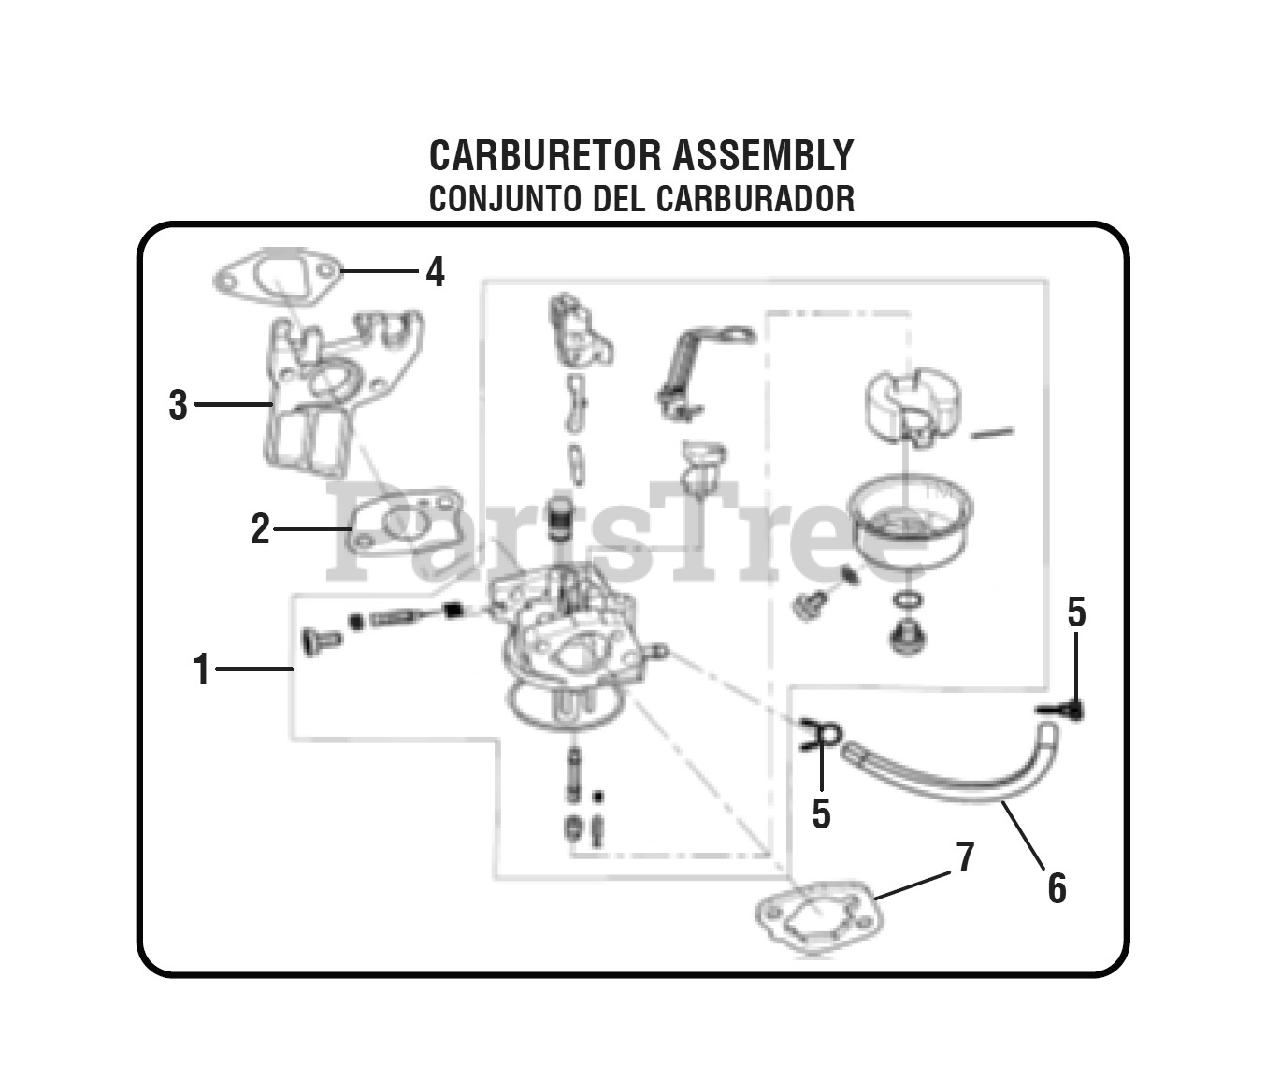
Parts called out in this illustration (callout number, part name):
1	Carburetor Assembly
2	Carburetor Gasket
3	Carburetor Insulator Plate
4	Carburetor Insulator Gasket
5	Clamp
7	Air Cleaner Gasket
